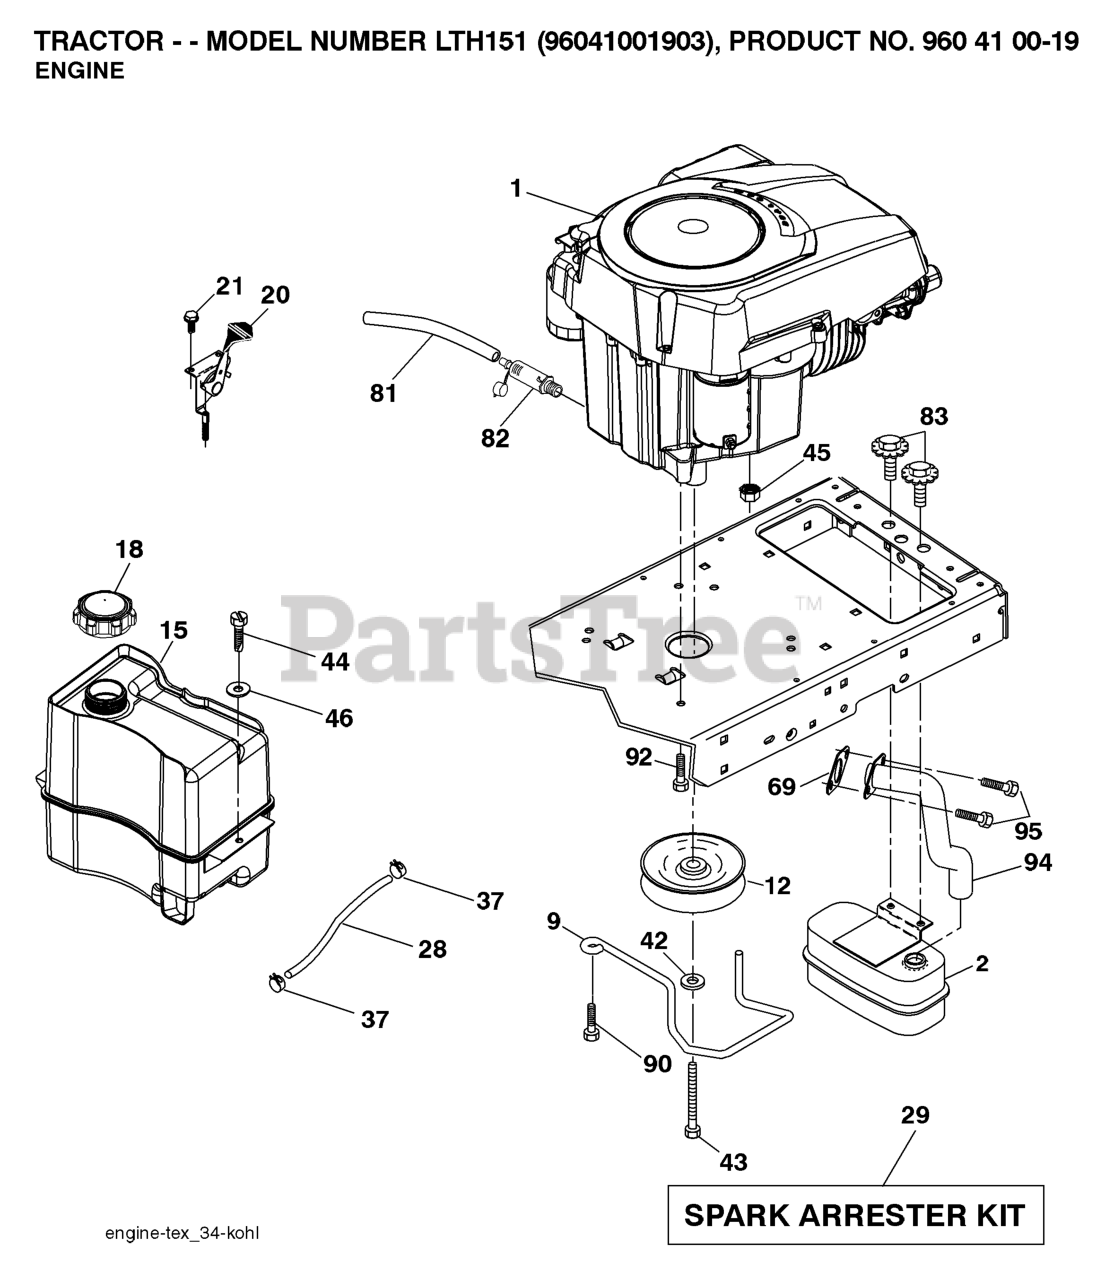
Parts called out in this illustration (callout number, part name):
2	MUFFLER.SINGLE.CYL.KOHL/B&S
9	KEEPER.BELT.ENGINE.3.25 (3 2)
12	PULLEY ENGINE
15	RP TANK FUEL FRT 1.5 GAL
18	FUEL CAP
20	CONTROL.TH/CK.C.
21	SCREW
28	LINE.FUEL.20
29	KIT.SPARK ARRESTOR 794945 B&S
37	HOSE CLAMP
42	LOCKWASHER
44	SCREW HEXWSHR 1/4-20X3/4
45	NUT
46	WASHER
69	GASKET.EXHAUST.KOHLER
79	SCREW.SOCKET HD.5/16-1
81	TUBE, DRAIN OIL ASM.
82	PLUG DRAIN OIL EASY
83	BOLT.5/16-18UNCX3/4 W/SEMS.BLK
90	SCREW 3/8-16X1
92	SCREW 3/8-16X1
94	RP.TUBE.EXHAUST.KOHL.COURAGE
95	BOLT HEX 7/16-20X4-1/4"
102	SCREW
105	SHIELD.SIDE.LH.3842"TEX FRENCH
106	SHIELD.SIDE.RH.3842"TEX FRENCH
107	SCREW.1/4-20X5/8
